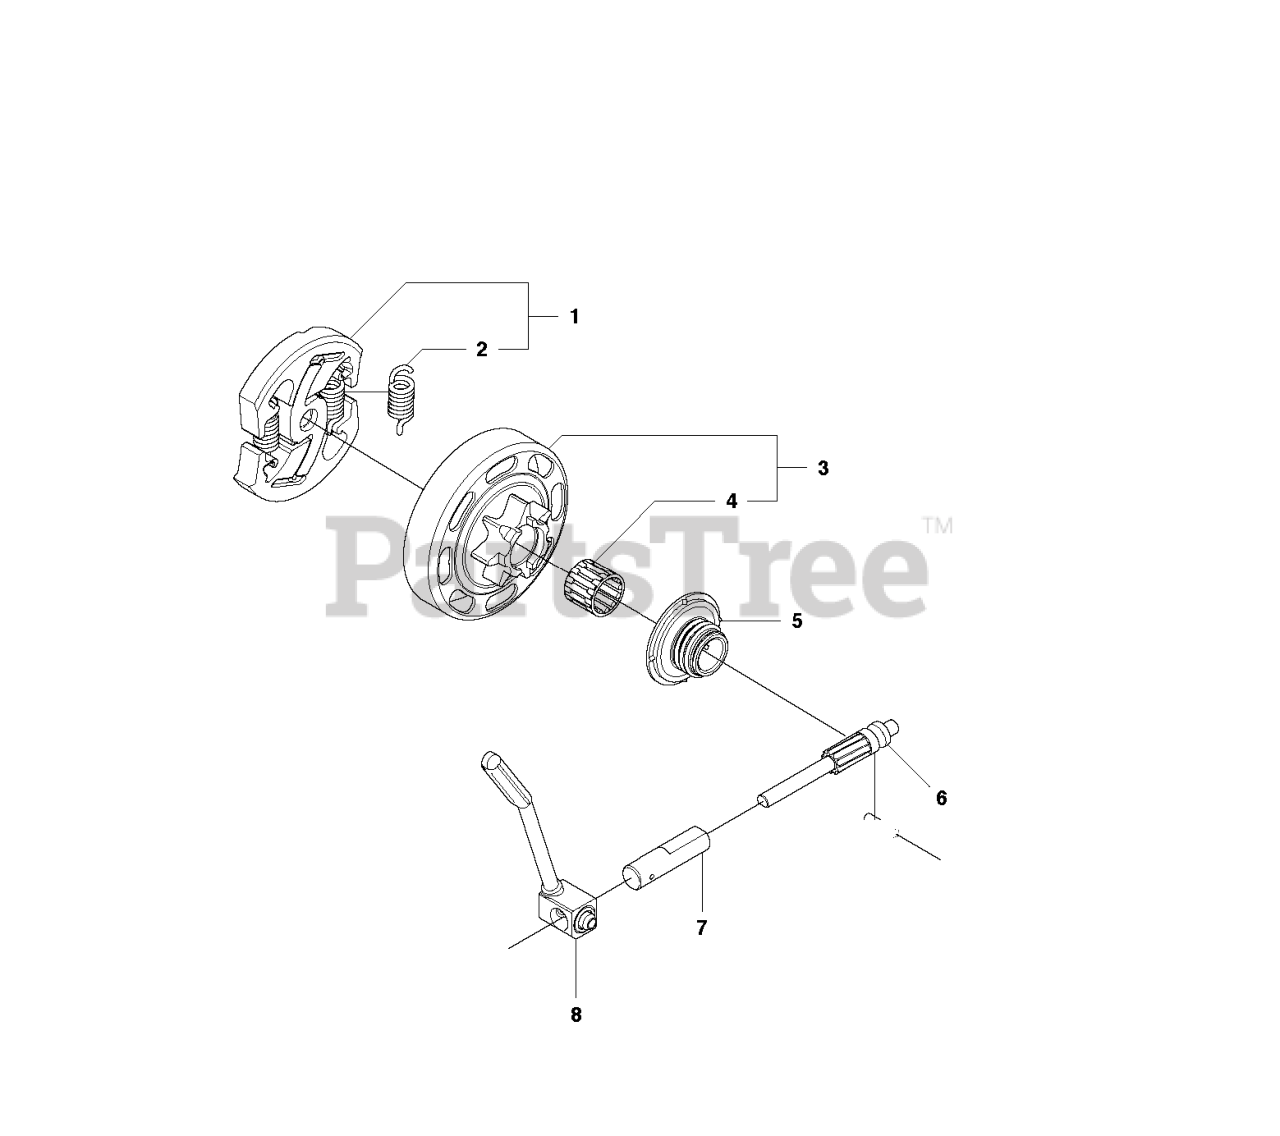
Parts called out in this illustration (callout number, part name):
1	CLUTCH ASSY
2	CLUTCH SPRING
3	CLUTCH DRUM ASSY
4	SUPPORT BUSHING
5	RP_WORM GEAR
6	PISTON PUMP
7	PUMP CYLINDER
